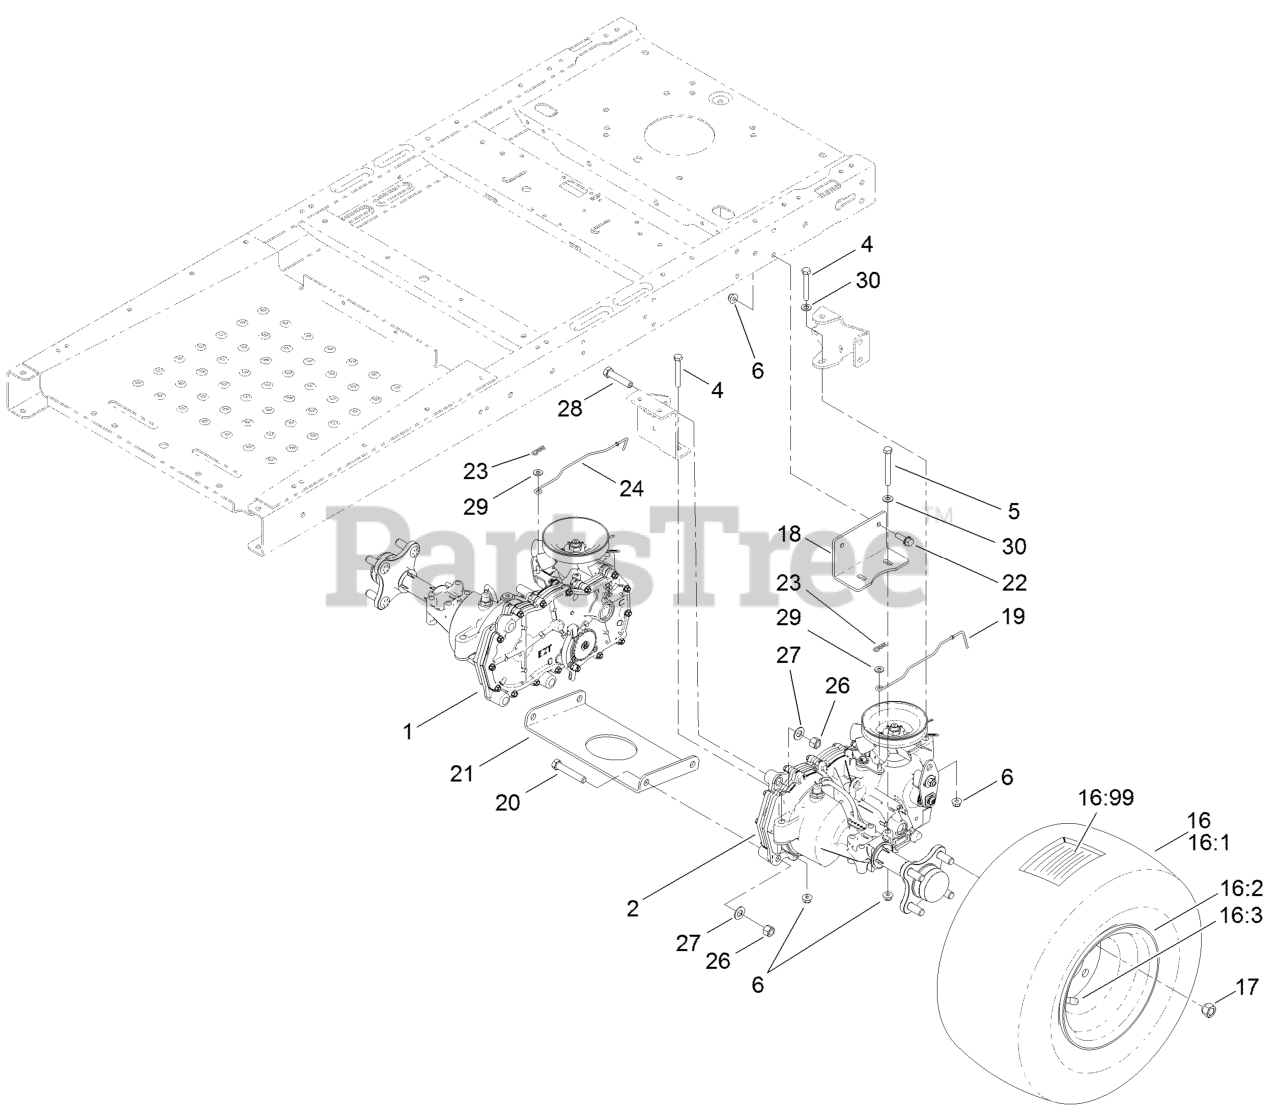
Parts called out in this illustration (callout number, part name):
3	SCREW-CARR
6	NUT-HF, NI
7	SCREW-HH
8	SPRING-RETURN, PEDAL
9	WASHER-PIVOT
10	V-BELT
11	PULLEY-IDLER
12	PULLEY-IDLER
13	ARM-IDLER
15	SPACER-ARM, IDLER
25	WASHER-FLAT
